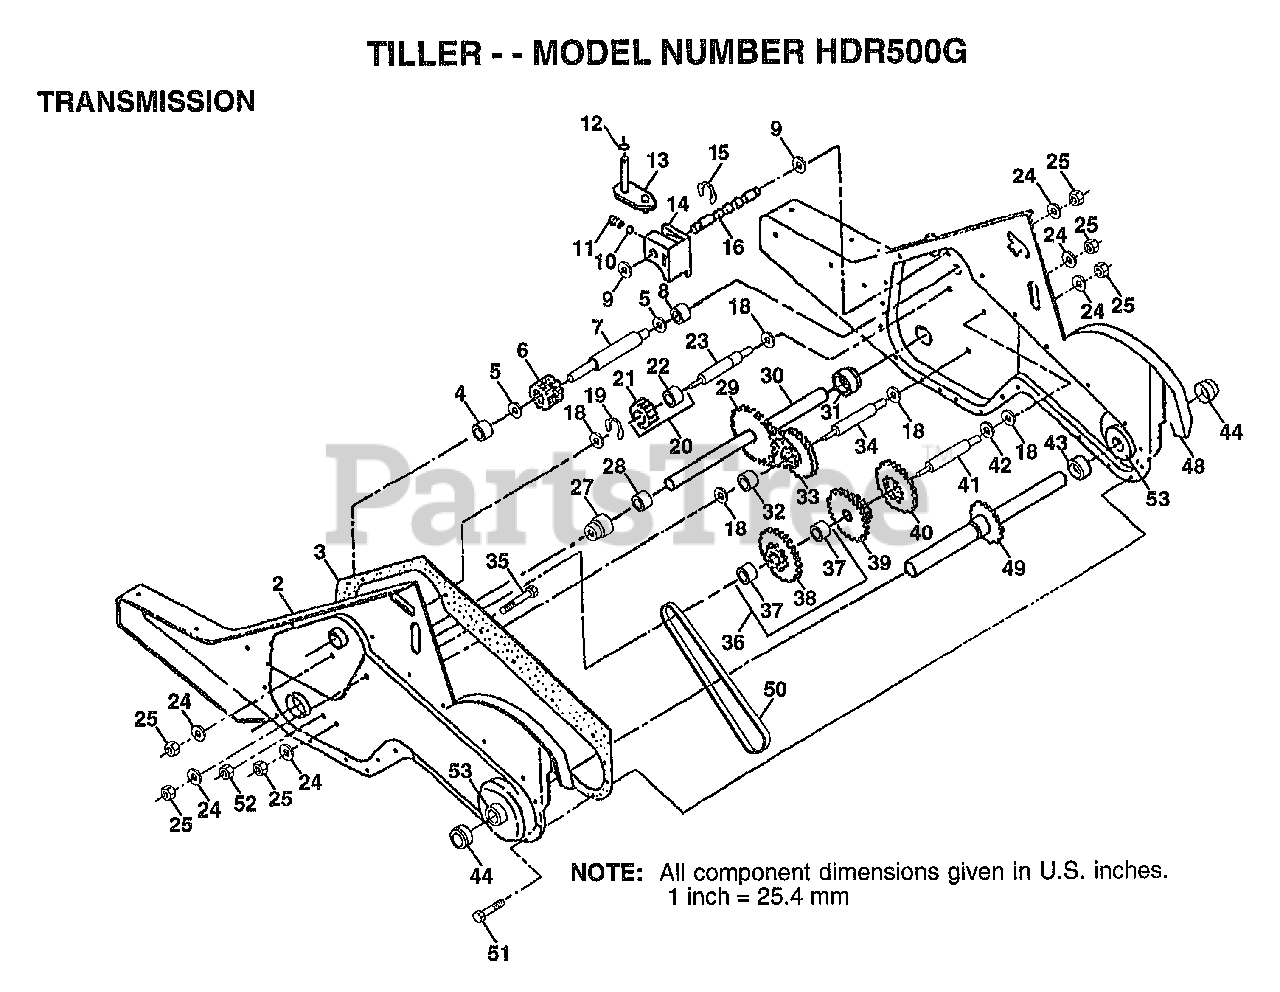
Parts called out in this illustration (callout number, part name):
2	GEARCASE LH W/BRG
3	GASKET TI
4	NEEDLE BRNG LT
5	"T, BEARING"
6	GEAR PINION INPUT
7	"SHAFT.INPUT.""D"""
8	"TI, BEARING"
9	WASHER SEAL
11	SPRING-SHIFT CRT
12	O-RING TI
13	BRACKET ASM SHIFT
14	SHIFT FORK TI
15	KLIP RING
16	SHAFT.SHIFTER
18	WASHER
19	KLIP RING
20	GEAR ASSY CRT
21	GEAR-REV IDLR CRT
22	NEEDLE BEARING TI
23	SHAFT CRT
24	LOCKWASHER
25	NUT.ASF.HEX.7/16
27	BEARING.SHAFT.LH.
28	BUSHING TI
29	CHAIN CRT
30	GROUND SHAFT ASSY
31	BEARING.SHAFT.RH.
32	SPACER TI
33	SPRCKT 8 GEAR CRT
34	SHFT 2ND RED. CRT
35	SCRW WHIZ LOK CRT
36	SPROCKET.ASM.W/BR
37	BEARING
39	GEAR TI
40	GEAR TI
41	REDUCTION SHFT TI
42	BRNG RACE
43	SPACER TI
44	SEAL ASM-OIL
48	GEARCASE RH W/BRG
49	TINE SHAFT
50	CHAIN.50 LINK TI
51	SCREW
52	NUT.HEX.5/16-18
